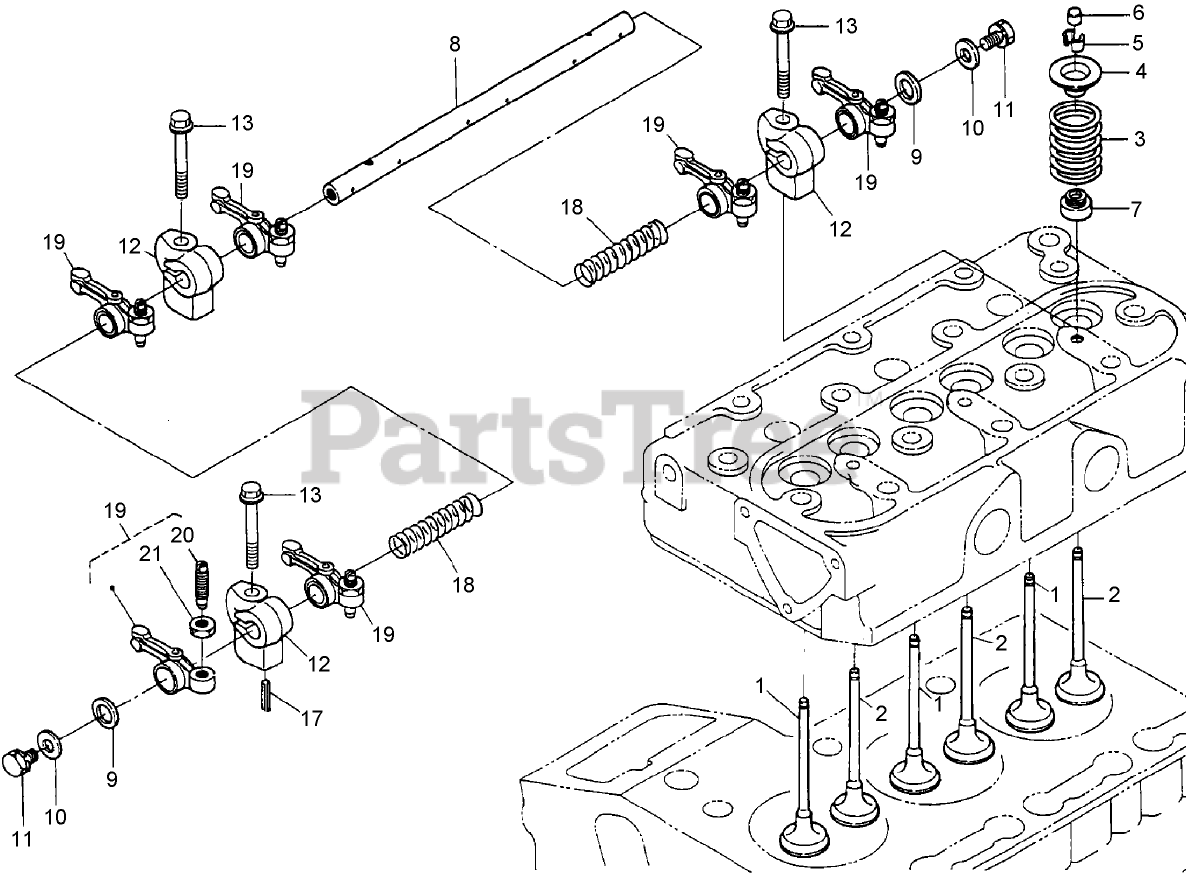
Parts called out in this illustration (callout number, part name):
1	VALVE-INLET
2	VALVE-EXHAUST
3	SPRING-VALVE
4	RETAINER-SPRING, VALVE
5	COLLET-SPRING, VALVE
6	CAP-VALVE
7	SEAL-STEM, VALVE
8	SHAFT-ARM, ROCKER
9	WASHER
10	WASHER-PLAIN
12	BRACKET-ARM, ROCKER
13	BOLT-FLANGE
17	PIN-SPRING
18	SPRING-ARM, ROCKER
19	ROCKER ARM ASM
20	SCREW-ADJUSTING
